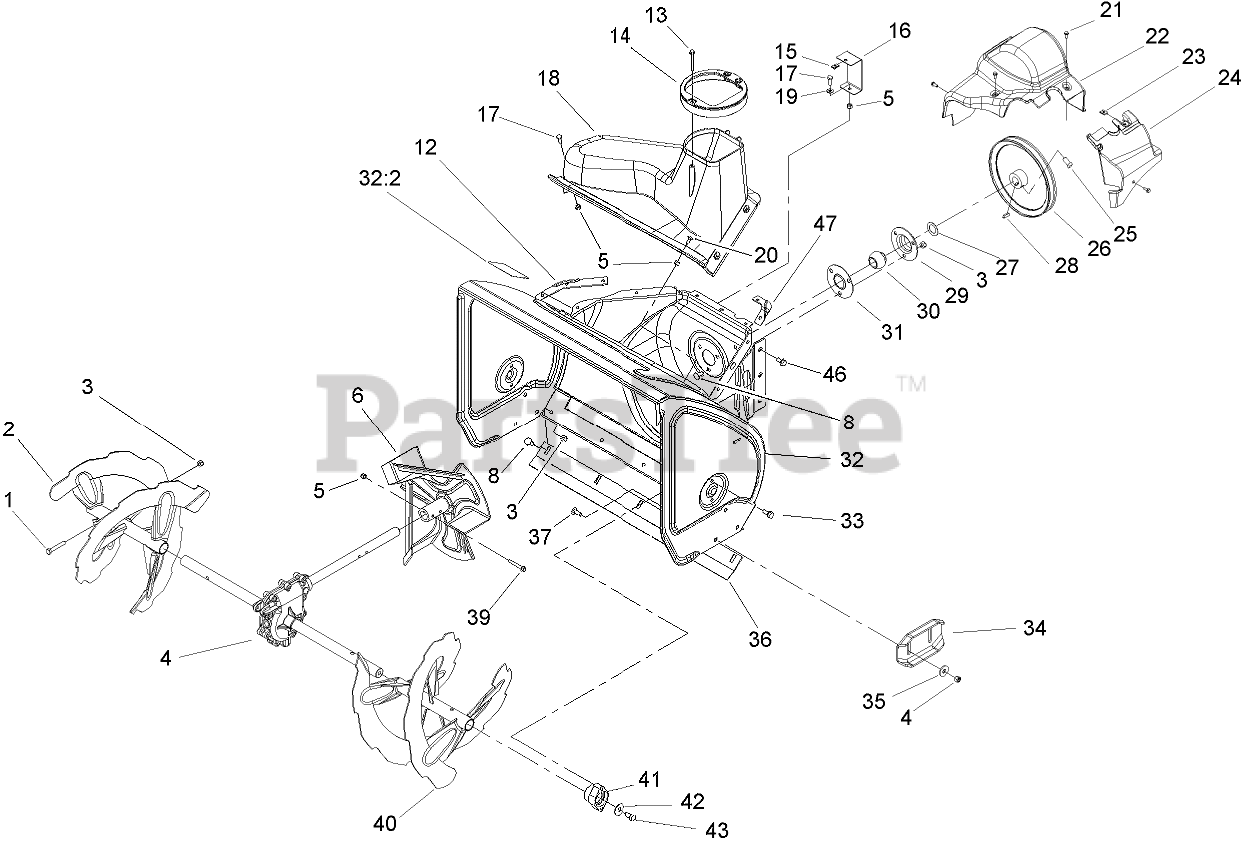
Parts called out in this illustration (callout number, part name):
1	SCREW-HH
2	RH AUGER ASM
3	NUT-LOCK, NI
4	26INCH AUGER GEARCASE ASM
5	NUT-LOCK, NI
6	IMPELLER ASM
8	SCREW-CARR
12	SEAL-FLANGE, COVER
13	SCREW-PLASTITE
14	GUIDE-CHUTE
15	NUT-SPEED, U-TYPE
16	BRACKET-COVER, CLIP NUT
17	SCREW-HH
19	WASHER-FLAT
20	BOLT-CARR
21	SCREW-HWH
22	COVER-BELT
23	NUT-SPEED
24	COVER-EXTENSION, BELT
25	SCREW-SET, SQH
26	PULLEY-IMPELLER
27	WASHER-THRUST
28	KEY-WOODRUFF
29	FLANGE-CUP, BEARING
30	BEARING-BALL
31	FLANGE-CUP, BEARING
32	HOUSING-AUGER, 26 INCH
32:2	DECAL-WARNING, AUGER
33	SCREW-HWHTF
35	WASHER
36	SCRAPER-FIXED
37	SCREW-CARR
39	SCREW-HHF
40	LH AUGER ASM
41	BEARING-AUGER
42	WASHER
43	SCREW-HH
46	SCREW-HWHTF
